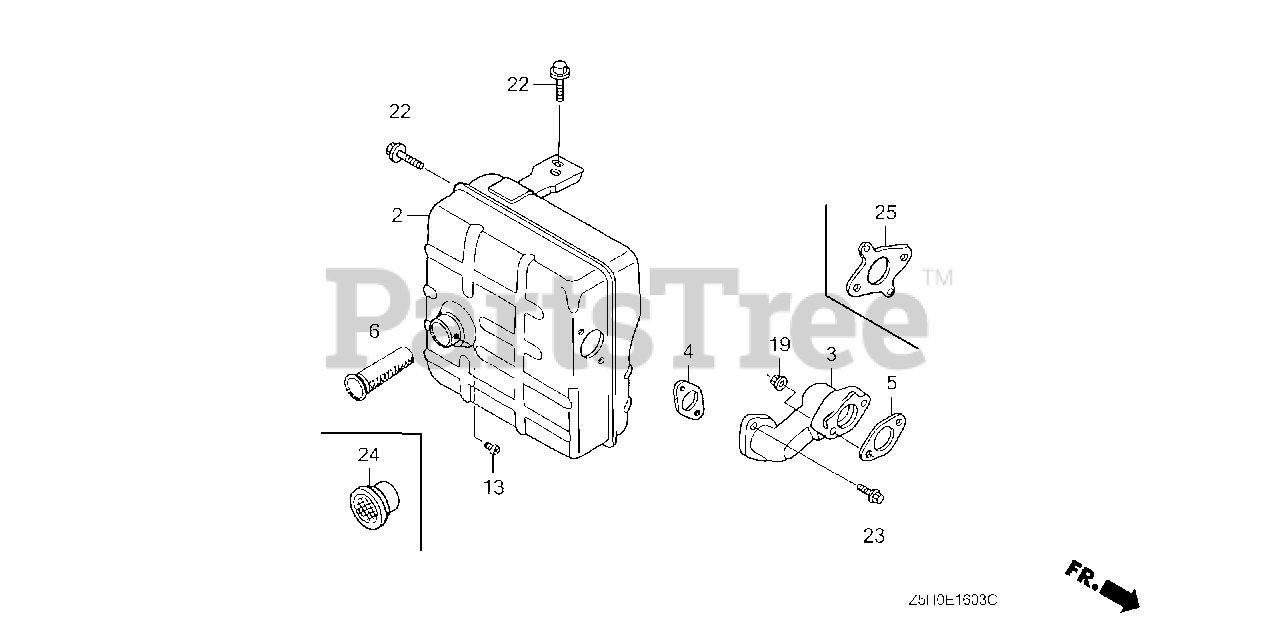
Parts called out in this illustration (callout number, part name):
2	MUFFLER (SDMO)
4	GASKET, EX. PIPE
5	GASKET, EX. PIPE
6	ARRESTER, SPARK
13	SCREW, TAPPING (4X8)
19	NUT, FLANGE (8MM)
22	BOLT, FLANGE (8X16)
23	BOLT, FLANGE (8X20)
25	GASKET, EX. PIPE
